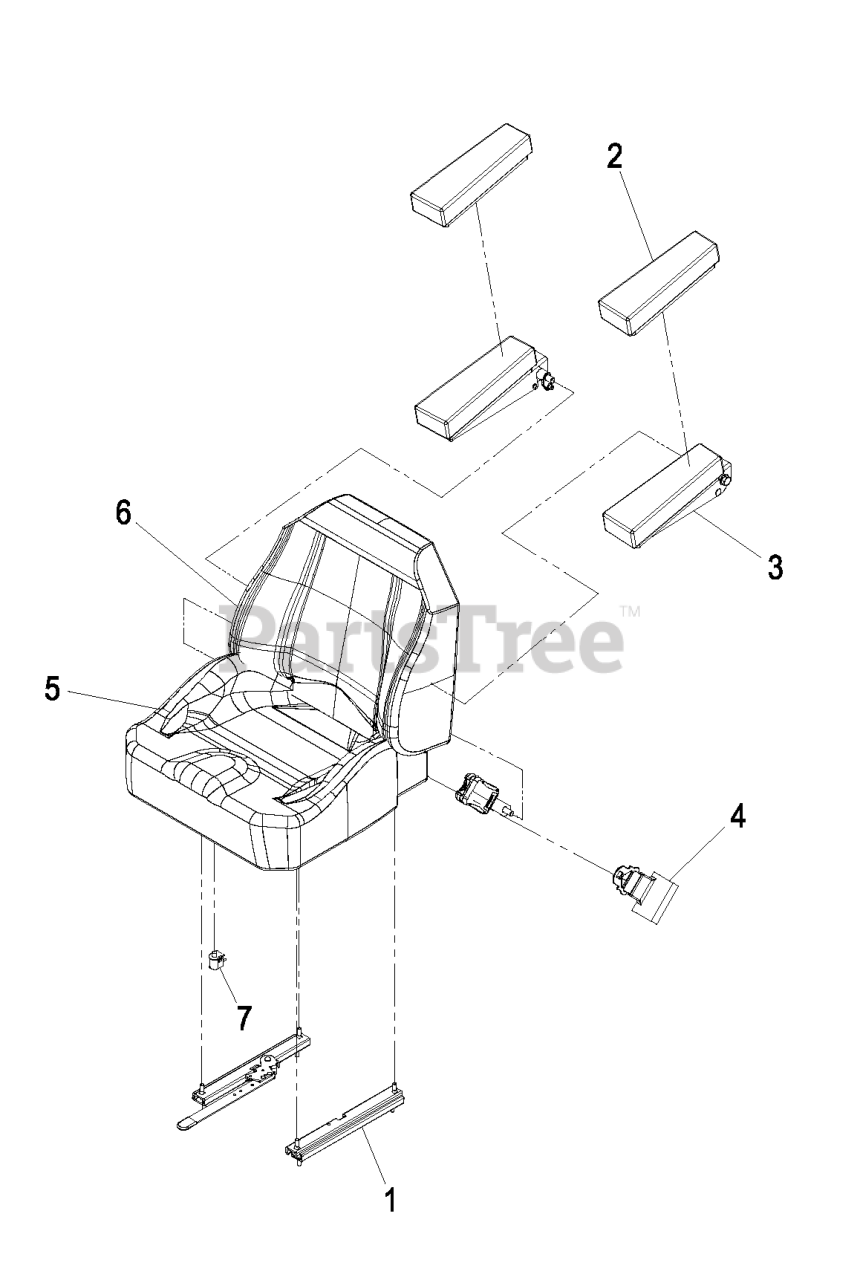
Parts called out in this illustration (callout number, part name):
1	SEAT TRACK SET
2	SET,ARM REST PADS
3	KIT,ARM REST SET
4	SEAT BELT KIT
5	COVER,CUSHION
6	COVER,BACK
7	SWITCH-BAIL
